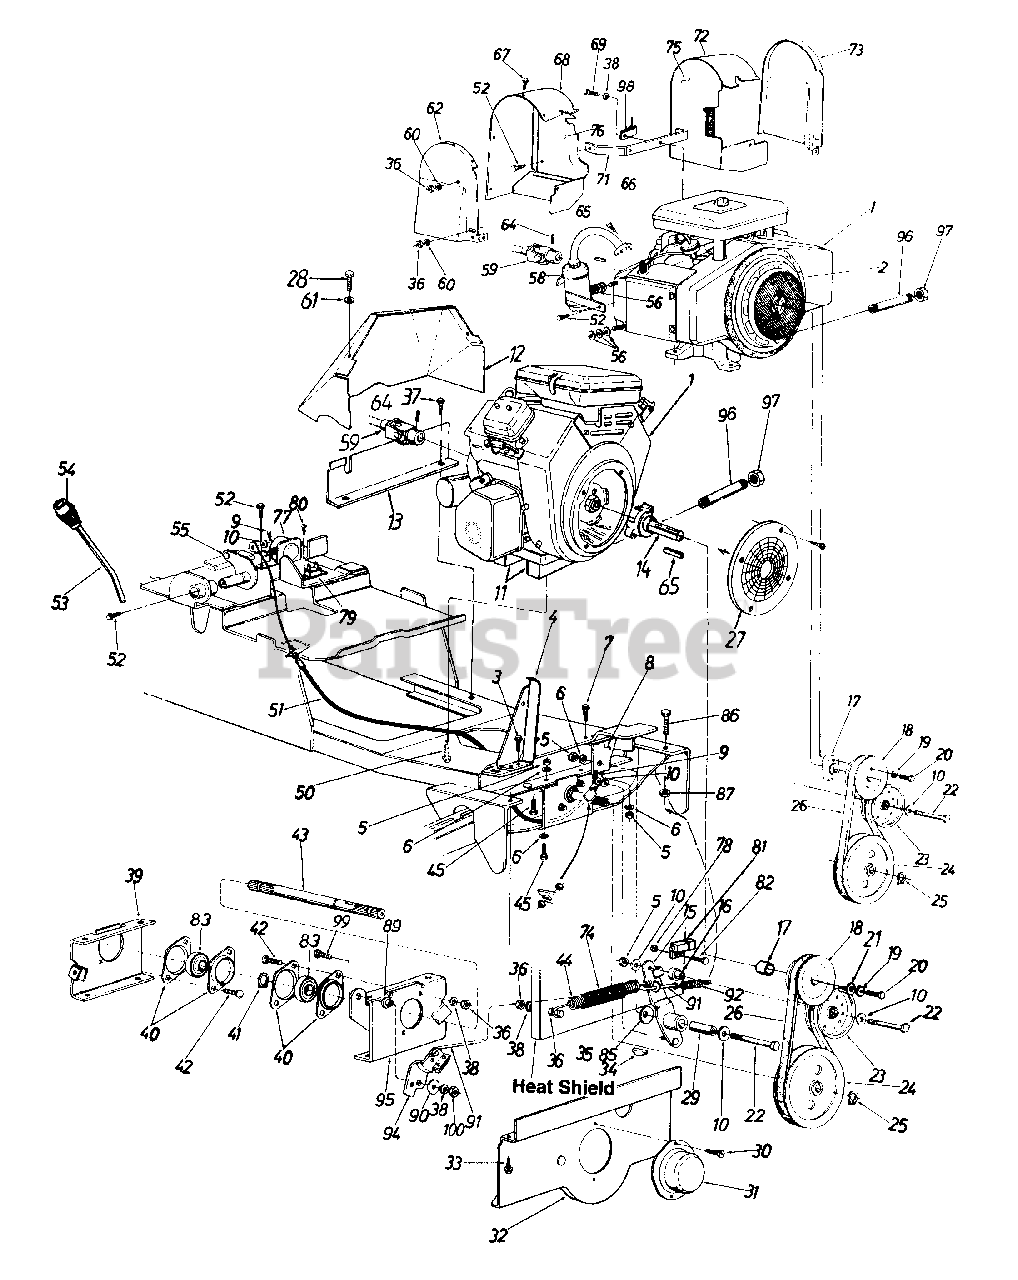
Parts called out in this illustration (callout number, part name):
1	Engine
2	Mylar Foam Strip
3	Hex Wash. Hd. Self-Tap Scr. 1/4-20 x .75" Lg.
6	L-Wash. 3/8" I.D.
7	Hex Wash. Hd. Self-Tap Scr. 5/16-18 x .75" Lg.
10	Fl-Wash. .38" I.D. x 1.25" O.D. x .100" Thk.
11	Engine Spacer Brkt
14	Crankshaft Ext.
17	Pulley Space
18	Engine PTO - Pulley
19	L-Wash. 3/8" I.D. H.D.
20	Hex Scr. 3/8-16 x 2.00" Lg.
21	Fl-Wash. 3/8" I.D. x 1.37" O.D.
22	Hex Bolt 3/8-16 x 2.50" Lg.
23	Flat Idler Pulley
24	1/2" V-Pulley 7.00" O.D. (PTO)
26	"V"-Belt (PTO)
27	Engine Screening
28	Hex Bolt M6-1.0 x 10 MM Lg.
29	Spacer .375" I.D. x .62" O.D. x 1.830" Lg.
30	Hex "B" Tap Scr. #10 x .50" Lg.
34	#91 Hi-Pro Key
35	Hex Bolt 5/16-18 x 1.25" Lg.
36	Hex Nut 5/16-18 Thd.
37	Hex Wash. Hd. Tap Scr. 5/16-18 x .5" Lg.
38	L-Wash. 5/16" I.D.
40	1.00" Dia. Brg. w/Flangette
42	Carr. Bolt 5/16-18 x .75" Lg.
43	Spline Shaft
44	Extension Spring
45	Hex Scr. 3/8-16 x 1.00" Lg.
50	Hex Wash. Hd. Self-Tap Scr. 3/8-16 x 1.25" Lg.
51	PTO Control Cable
52	Hex Wash. Hd. Self-Tap Scr. 1/4-20 x .50"
55	PTO Actuator Lever Ass'y.
56	Fl-Wash. .312" I.D. x 1.620"
58	Muffler Ass'y. Comp. - R.H.
59	Universal Drive Shaft Comp.
60	Fl-Wash. .312" I.D. x .630"
61	Fl-Wash. .281" I.D. x .5" O.D.
62	Shroud Outer - R.H.
64	Set Scr. 5/16-18 x .38" Lg.
65	Sq. Key 1/4" x 2.00" Lg.
66	Hex Wash. Hd. Scr. 1/4-20 x 5/8" Lg. - Grade 5
67	Hex "AB" Tap Scr. #10 x .50" Lg
68	Shroud Cover - R.H.
69	Hex Bolt 5/16-24 x .75" Lg.
71	Shroud Support Brkt.
72	Shroud Cover - L.H.
73	Shroud Outer - L.H.
74	Spring Cover Tubing
75	Shroud Inner Ass'y. - L.H.
76	Shroud Inner Ass'y. - R.H.
77	Solenoid
78	Hex Bolt 1/4-20 x 1/2" Lg.
79	Circuit Breaker
80	Truss Mach. Scr. #10 x .50" Lg.
81	Safety Switch
82	L-Wash. 1/4" I.D.
83	Ball Bearing
85	Bell-Wash. .39" I.D. x 1.13"
86	Hex Bolt 3/8-16 x 1.5" Lg.
87	Hex Cent. L-Nut 3/8-16 Thd.
89	Shoulder Spacer
90	Fl-Wash. .33" I.D. x 1.25" O.D.
91	PTO Brake Rod
92	Extension Spring 2.15" Lg.
95	PTO Brg. Retainer Brkt. Ass'y.
96	Pipe Nipple 3/8" x 5" Lg.
97	Oil Drain Cap
99	Hex Bolt 5/16-24 x .75" Lg.
100	Hex Nut 5/16-24 Thd.
